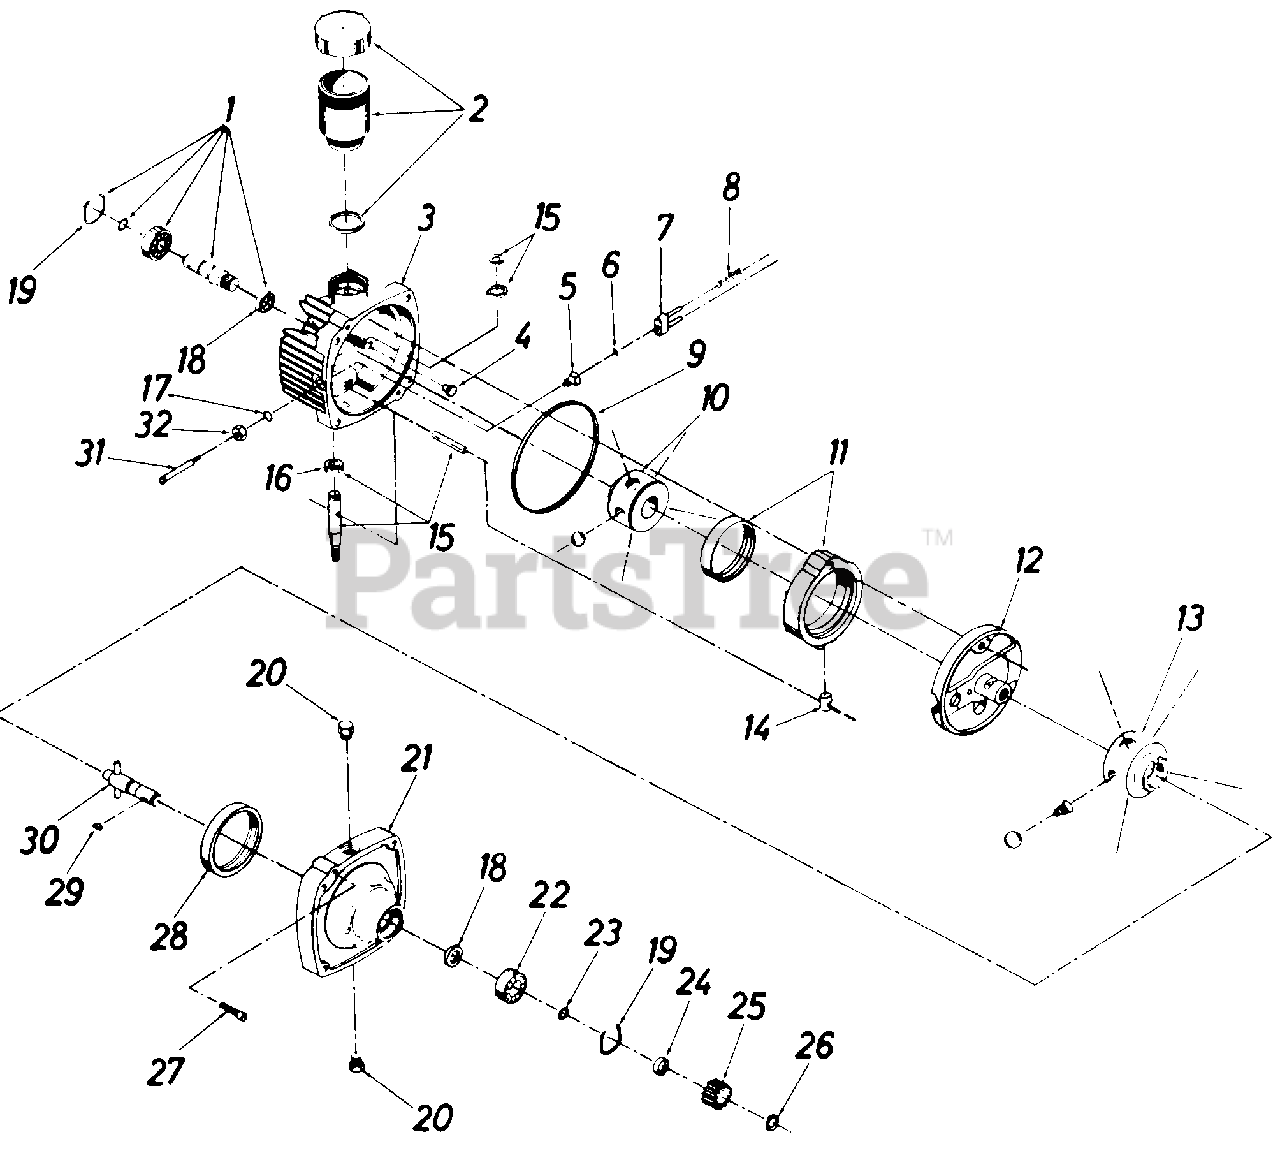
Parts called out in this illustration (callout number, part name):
1	Kit Input Shaft
2	Kit Reservoir
3	Kit Cover
4	Button
5	O-Ring Fitting Guide Subassembly
6	O-Ring
7	Bracket Pins Subassembly
8	Valve Spring
9	Square Cut Seal Ring
10	Pump Rotor Ball Subassembly
11	Cam Ring Subassembly
12	Pintle Subassembly
13	Motor Rotor Ball Subassembly
14	Cam Ring Insert
15	Kit Control Shaft
17	O-Ring .013
18	Oil Seal
19	Retaining Ring
20	O-Ring Plug Subassembly
21	Body
22	Ball Bearing (Output)
23	Snap Ring
24	Spacer
25	Drive Gear (12 Teeth)
26	External Retaining Ring
27	Socket Hd. Scr. 5/16-18 x 1.25" Lg.
28	Motor Race
29	Woodruff Key #3
30	Output Shaft Subassembly
31	Dump Valve Shaft
32	Nut Gasket Subassembly
